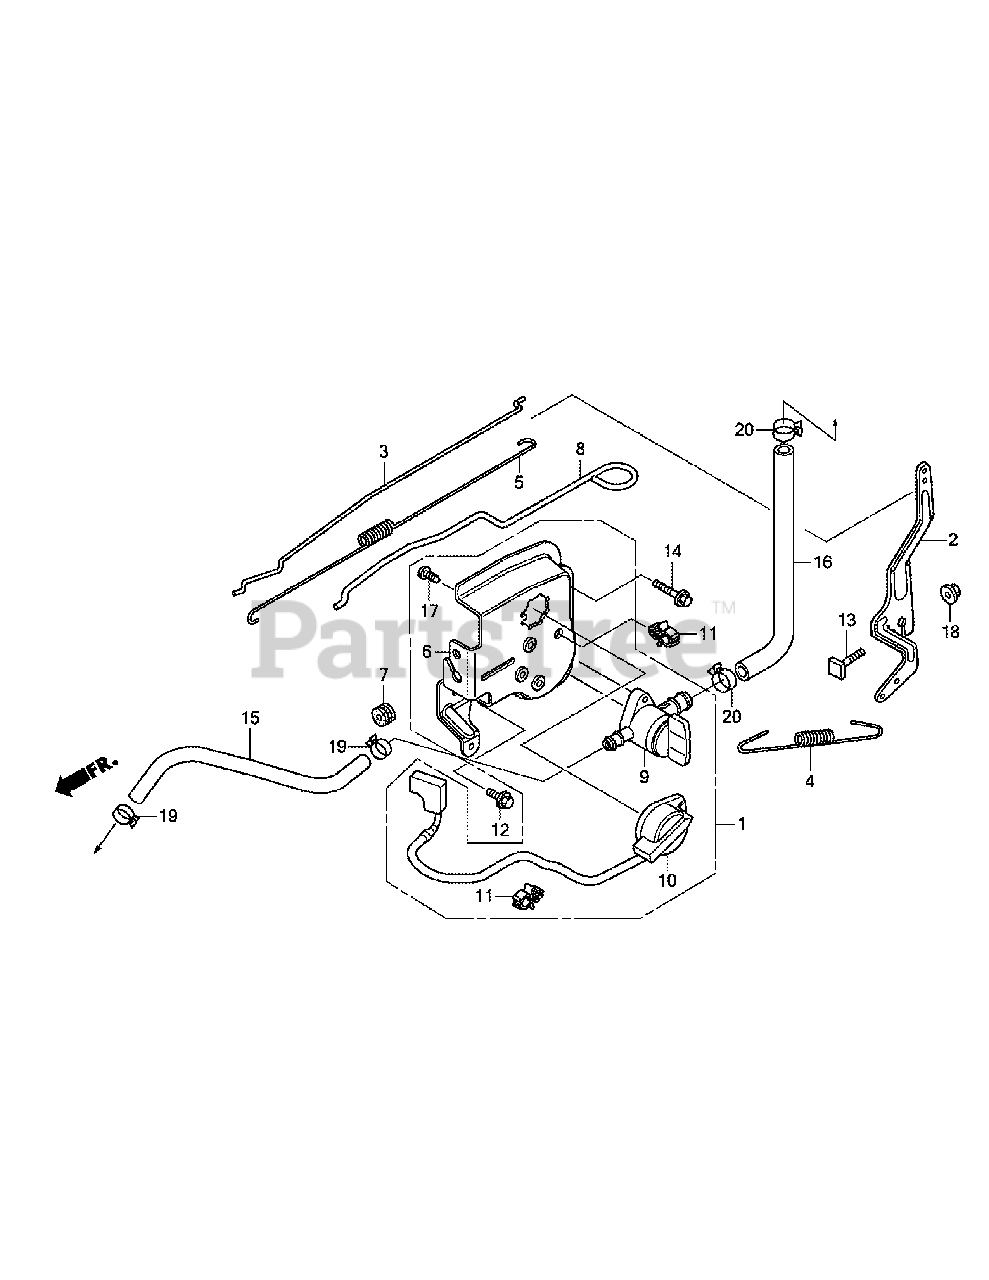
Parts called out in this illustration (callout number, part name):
1	Governor Arm
2	Governor Rod
3	Governor Spring
4	Throttle Return Spring
6	Control Base
8	Choke Rod Grommet
11	Engine Stop Switch Assembly
12	Wire Holder
12	Cable Clip
13	Governor Arm Bolt
14	Flange Bolt, 6 x 45
15	FlangeNut, 6mm
